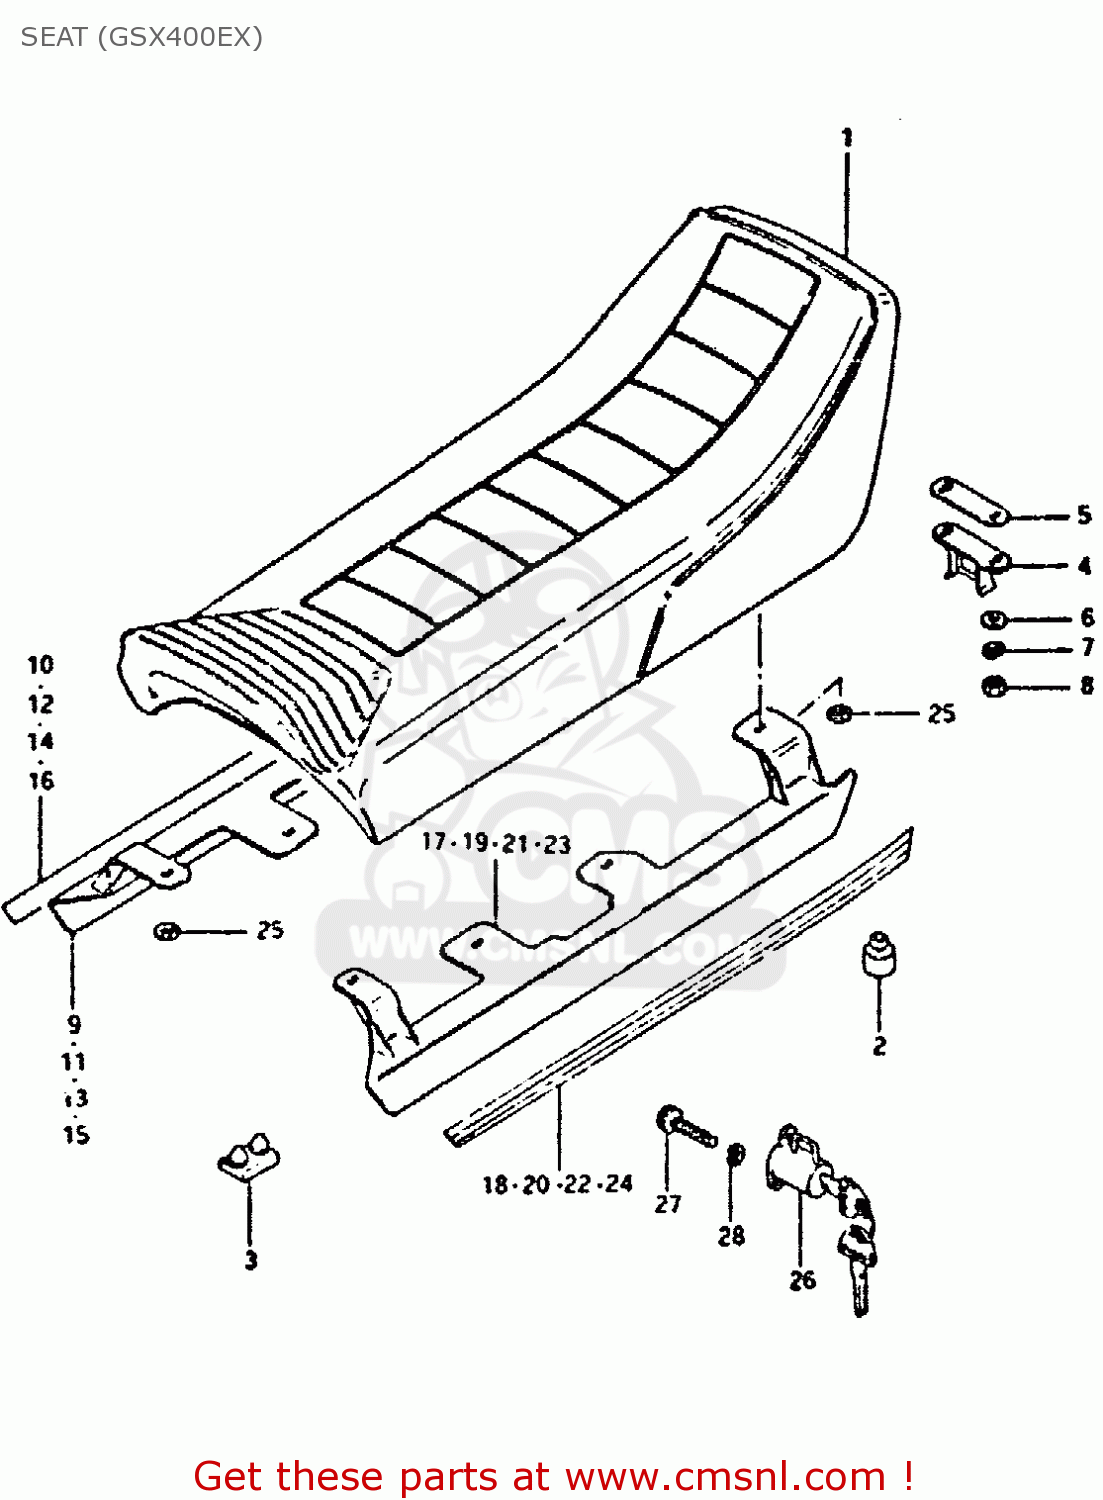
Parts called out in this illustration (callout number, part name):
1	SEAT ASSEMBLY
2	CUSHION
3	CUSHION
4	STRIKER,SEAT LOCK
5	SHIM,SEAT LOCK STRIKER
6	WASHER
7	LOCK WASHER
8	NUT 6MM
9	MOLDING,SEAT
10	TAPE, RH
11	MOLDING,SEAT
12	TAPE, RH
13	MOULDING, SEAT RH (BLUE)
14	TAPE, RH
15	MOLDING,SEAT
16	TAPE, RH
17	MOLDING,SEAT
18	TAPE, LH
19	MOLDING,SEAT
20	TAPE, LH
21	MOULDING, SEAT LH (BLUE)
22	TAPE, LH
23	MOLDING,SEAT
24	TAPE, LH
25	NUT
26	LOCK ASSEMBLY,HELMET
27	BOLT 6X11
28	LOCK WASHER
